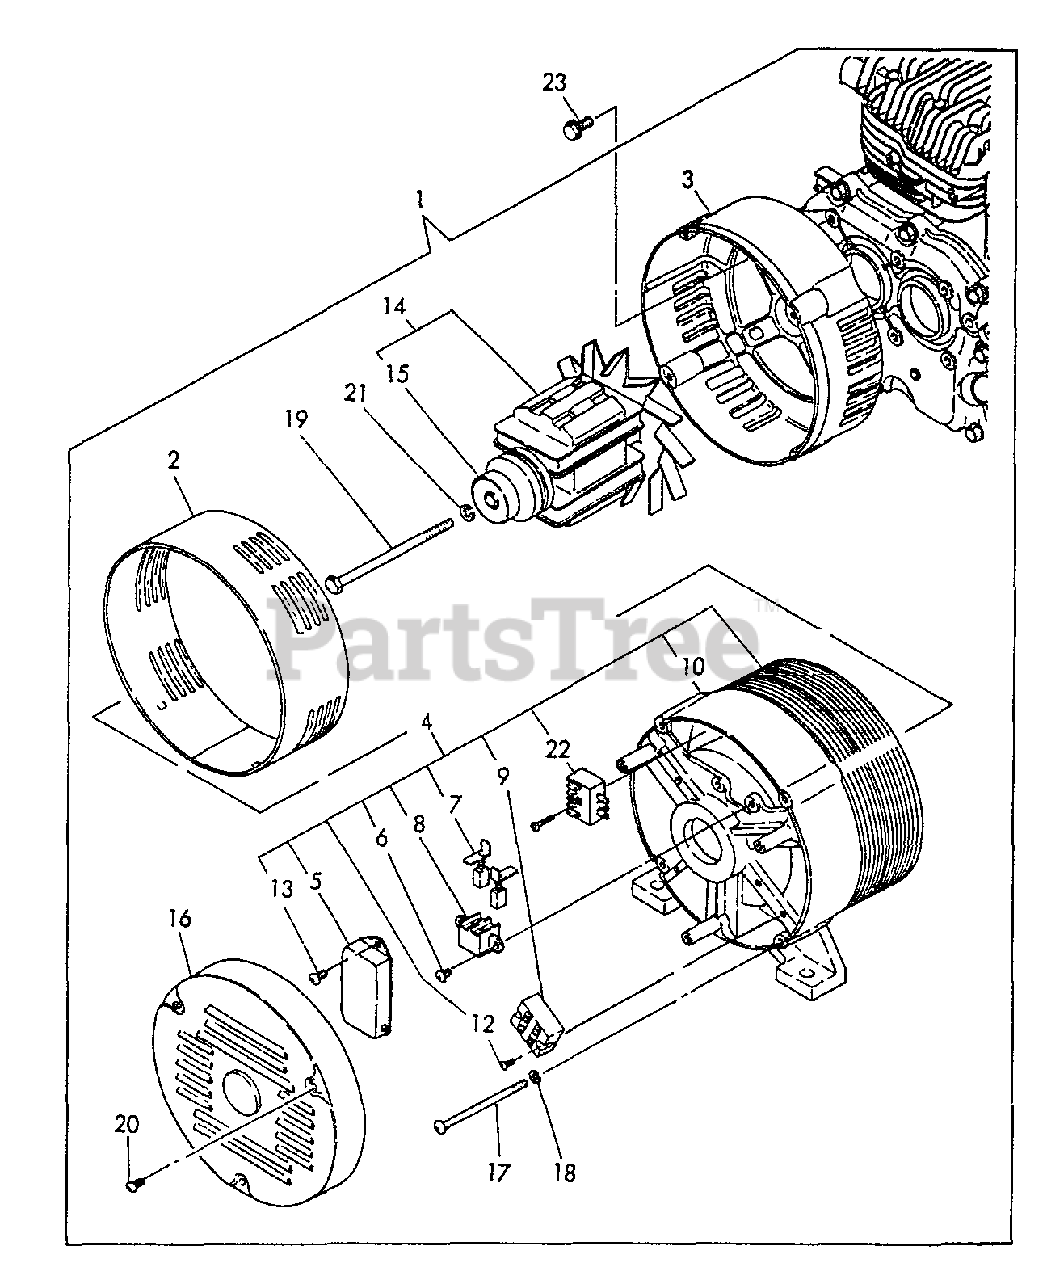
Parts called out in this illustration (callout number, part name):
1	GENERATOR 3.0 KVA
2	CLAMP
3	COVER - FRONT
4	STATOR ASSY
5	A.V.R.
6	SCREW - 5X14
7	BRUSH ASSY
8	HOLDER, BRUSH
9	TERMINAL
10	COVER - REAR
12	SCREW - 5X14
13	SCREW - 4X14
14	ROTOR ASSY
15	BEARING, BALL
16	COVER, END
17	BOLT, THROUGH
18	LOCKWASHER - 6
19	BOLT
20	SCREW - 4X8
21	LOCKWASHER - 10
22	RECTIFIER
23	BOLT - 8X20 -- PLATED
